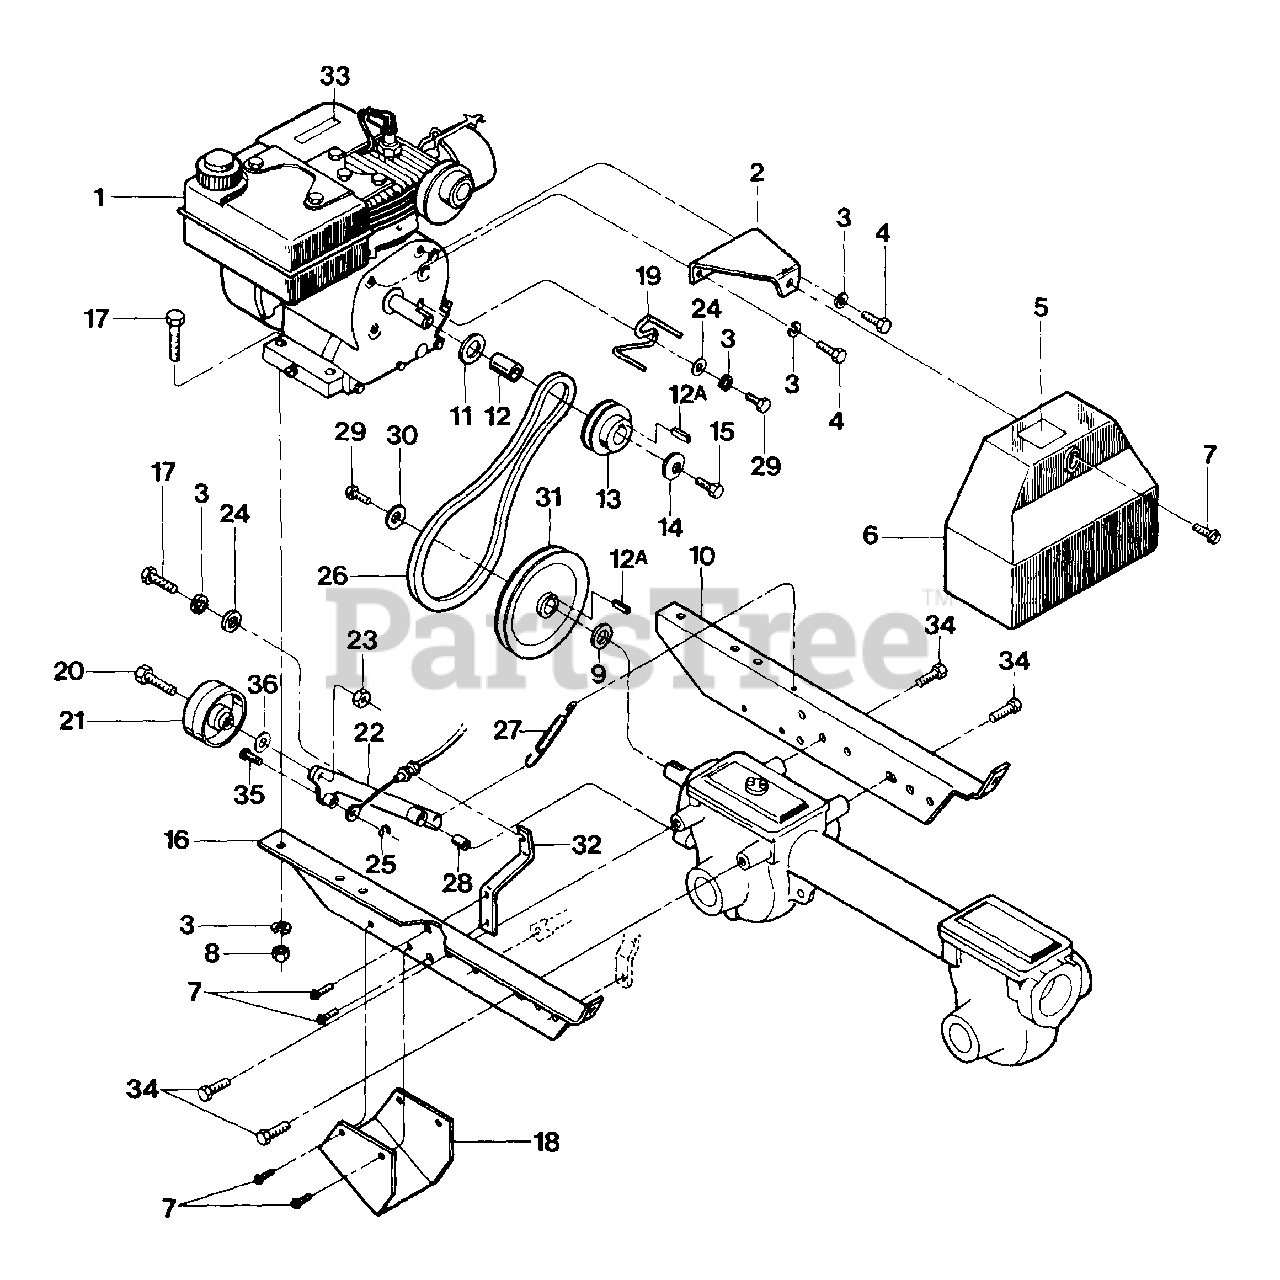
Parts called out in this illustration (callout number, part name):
1	Engine - Tecumseh, recoil start
2	Bracket, Belt Cover
3	Lockwasher - 5/16"
4	Bolt - Hex Hd, 5/16-24 x 1/2"
5	Decal - Warning, Hot Surfaces
6	Belt Cover
7	Bolt - Flanged Hd, Self-Tapping, 1/4-20 x 1/2"
8	Nut - Hex Hd, 5/16-18"
9	Support Washer
10	Bracket, Engine, Right
11	Shim
12	Spacer
12A	Key - 3/16" x 1"
13	Pulley, Engine Driven
14	Washer, Belleville
15	Bolt-Hex Hd, 3/8-24 x 1"
16	Bracket, Engine, Left
17	Bolt - Hex
18	Belt Pulley Guard
19	Belt Guide
20	Bolt - Hex Hd, 3/8-16 x 1-1/2"
21	Idler Pulley
22	Idler Lever
23	Locknut - 3/8-16"
24	Washer, Flat
25	Klip Ring
26	V-Belt
27	Spring, Return
28	Bushing - Idler Lever
29	Bolt - Hex Hd, 5/1 6-24 x 3/4" Grade 5
30	Washer, Belleville, Transmission Pulley
31	Pulley - Transmission
32	Bracket - Cable Mount
33	Decal - Stabilization
34	Bolt - 5/16-18 x 5/8" Engine Bracket to Transmission
35	Clevis Pin-Control Cable
36	Washer - flat, 3/8"
